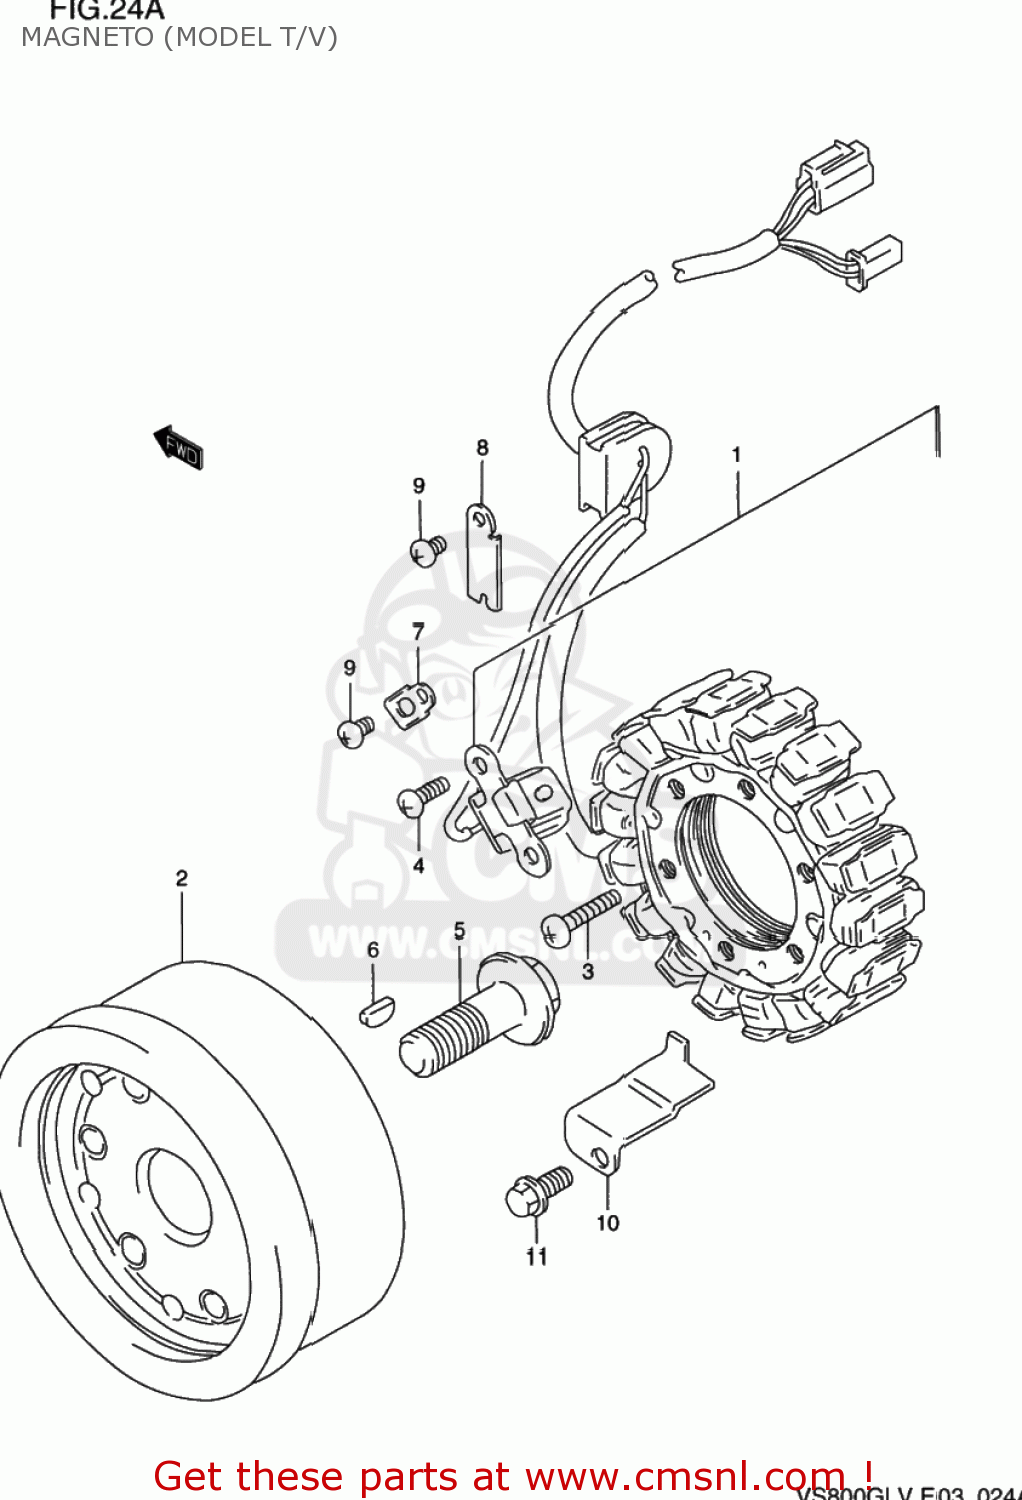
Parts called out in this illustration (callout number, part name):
1	STARTER ASSY
2	ROTOR ASSY
3	BOLT,G/S SWITC
4	SCREW
5	BOLT(14X43)
6	KEY
7	CLAMP,GENERATOR LEAD WIRE
8	CLAMP NO.1,MAGNETO READ WIRE
9	SCREW
10	CLAMP,MAGNETO LEAD WIRE
11	BOLT
